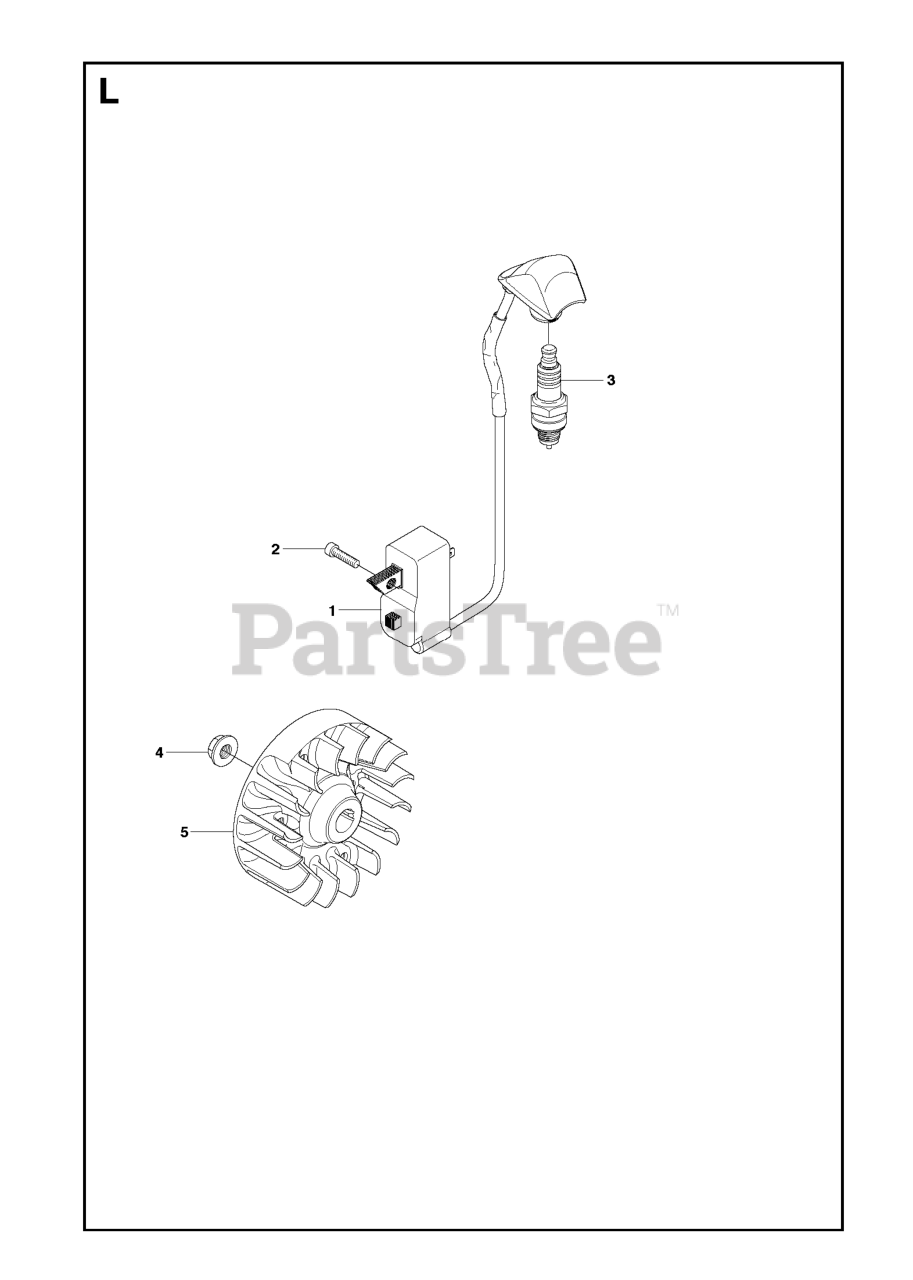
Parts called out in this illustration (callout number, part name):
1	IGNITION MODULE DM60CWS
3	SPARK PLUG M14X1.25 NGK BPMR7A
4	FLANGE NUT
5	FLYWHEEL
